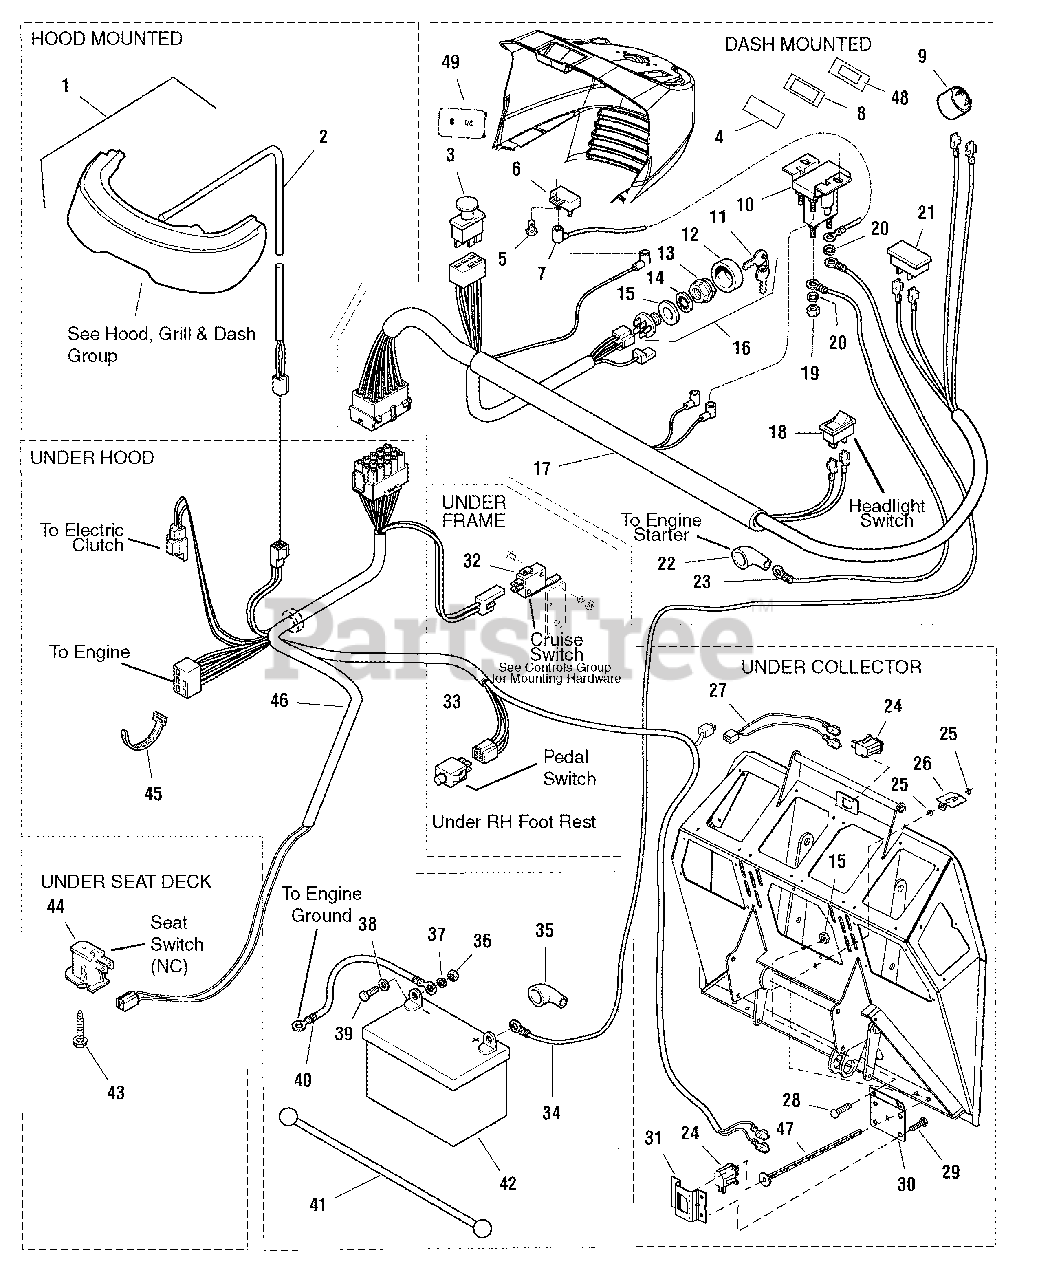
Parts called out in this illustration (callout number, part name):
1	HEADLIGHT ASSEMBLY
2	HARNESS, Headlight Assembly
3	SWITCH, PTO, Push/Pull
5	CAPSCREW, Hex Head, 1/4 x 5/8
6	BREAKER, Circuit 12Volt, 20Amps
7	WIRE, 12GA, 5.9" Long, Red
8	PLUG, Hole, 18HP Only
9	BUZZER, Pulse, Bag Full
10	SOLENOID
11	KEY, Ignition
12	COVER
13	NUT, Hex Flange, 5/8-32
14	LOCKWASHER, Internal Tooth, 5/8
16	SWITCH ASMY, Ignition, 6 Pin, (Includes Ref. Nos. 11, 12, 13, 14, & 15)
17	HARNESS, Wiring Upper
18	SWITCH, Headlights , 2 Terminal
19	NUT, Hex, 5/16-24 KEPS, Yellow
20	LOCKWASHER, External Tooth, 5/16
21	METER, Hour, 18HP
22	BOOT, Insulator
23	CABLE, # 6, 25" Long, Red
24	SWITCH, Push, Black
27	HARNESS, Rear
28	CARRIAGE BOLT1/4-20 x 5/8
29	CAPSCREW, Hex Head Taptite, 1/4-20 x 1/2
30	BRACKET, Switch
31	BRACKET, Hopper Switch
32	SWITCH, Cruise, Grey
33	SWITCH, Push Button Foot, Domestic Only, Black
33	SWITCH, Push Button Foot, Export Only, Black
34	CABLE, # 6, 9" Long
35	BOOT, Insulator Battery Terminal
36	NUT, Hex, 1/4-20
37	LOCKWASHER
38	WASHER
39	CAPSCREW, Hex Head, 1/4-20 x 3/4
40	CABLE, # 6, 26" Long
41	STRAP, Battery
42	BATTERY, 12 Volt
43	SCREW, Hex Washer Head Plastite, 1/4-20
44	SWITCH, Operator Present, NC, Grey
46	HARNESS, Wiring Lower
47	ROD & WASHER ASSEMBLY, Hopper
48	PLUG, Hole, 16hp Only
49	CLIP, Hour Meter
